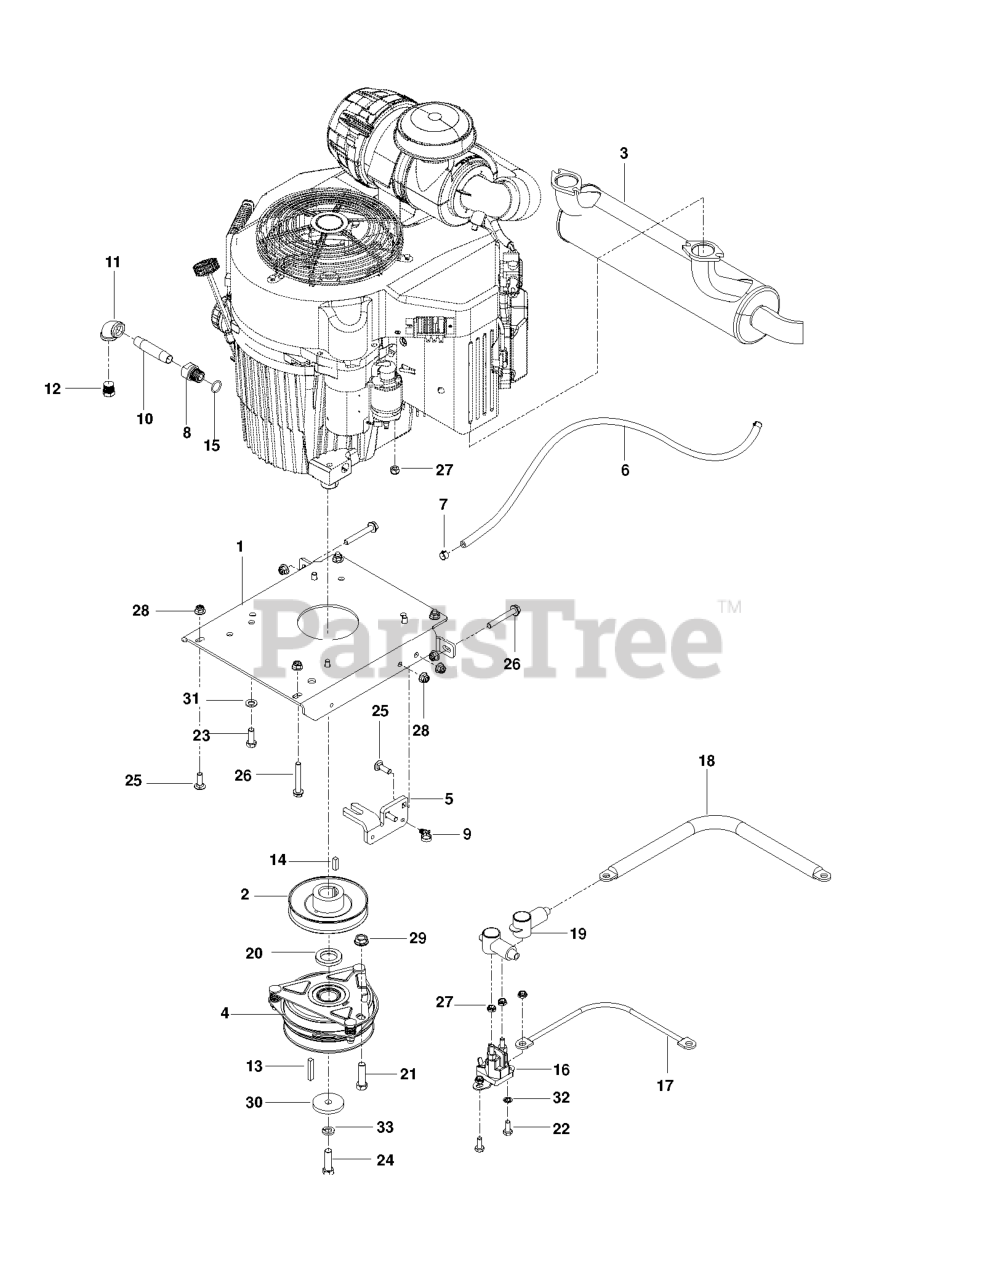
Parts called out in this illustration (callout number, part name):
1	PLATE.ENGINE.BLACK
2	PULLEY, ENGINE
3	MUFFLER.26HP.KAW.FX651V-730V
4	CLUTCH, 150 FT/LBS
5	STOP, CLUTCH, OGURA
6	FUEL LINE 18"
7	HOSE CLAMP
8	ADAPTER, OIL DRAIN
9	TIE WRAP, 8-3/8", W/CLIP
10	PIPE NIPPLE 3/8 X 3
11	90 DEG.ELBOW 3/8NPT
12	PLUG, DRAIN 3/8 NPTF
13	KEY 1/4 SQ X 2
14	KEY 1/4 SQ X 1.0
17	GROUND WIRE (KAW)
18	CABLE POSITIVE
20	SPACER, .25 X 1.135 I.D.
21	HCS 7/16-14 X 1-1/4 GR 5 ZD
22	HCS 1/4C X 5/8
23	HCS 3/8-16X1.GRD.5.ZD
24	HCS 7/16F X 1 1/2
25	RHSNB 5/16C X 1
26	HHFS 5/16-18 X 2.25 GD 5
27	JAM NUT 1/4C (2 2 PW01)
28	5/16-18 NYLOC FLANGE NUT
29	NUT 7/16C WHIZ
30	BLADE WASHER
31	WASHER, 3/8 DISC SPRING SPEC
32	WASHER 1/4 INT TOOTH
33	WASHER 7/16 LOCK
